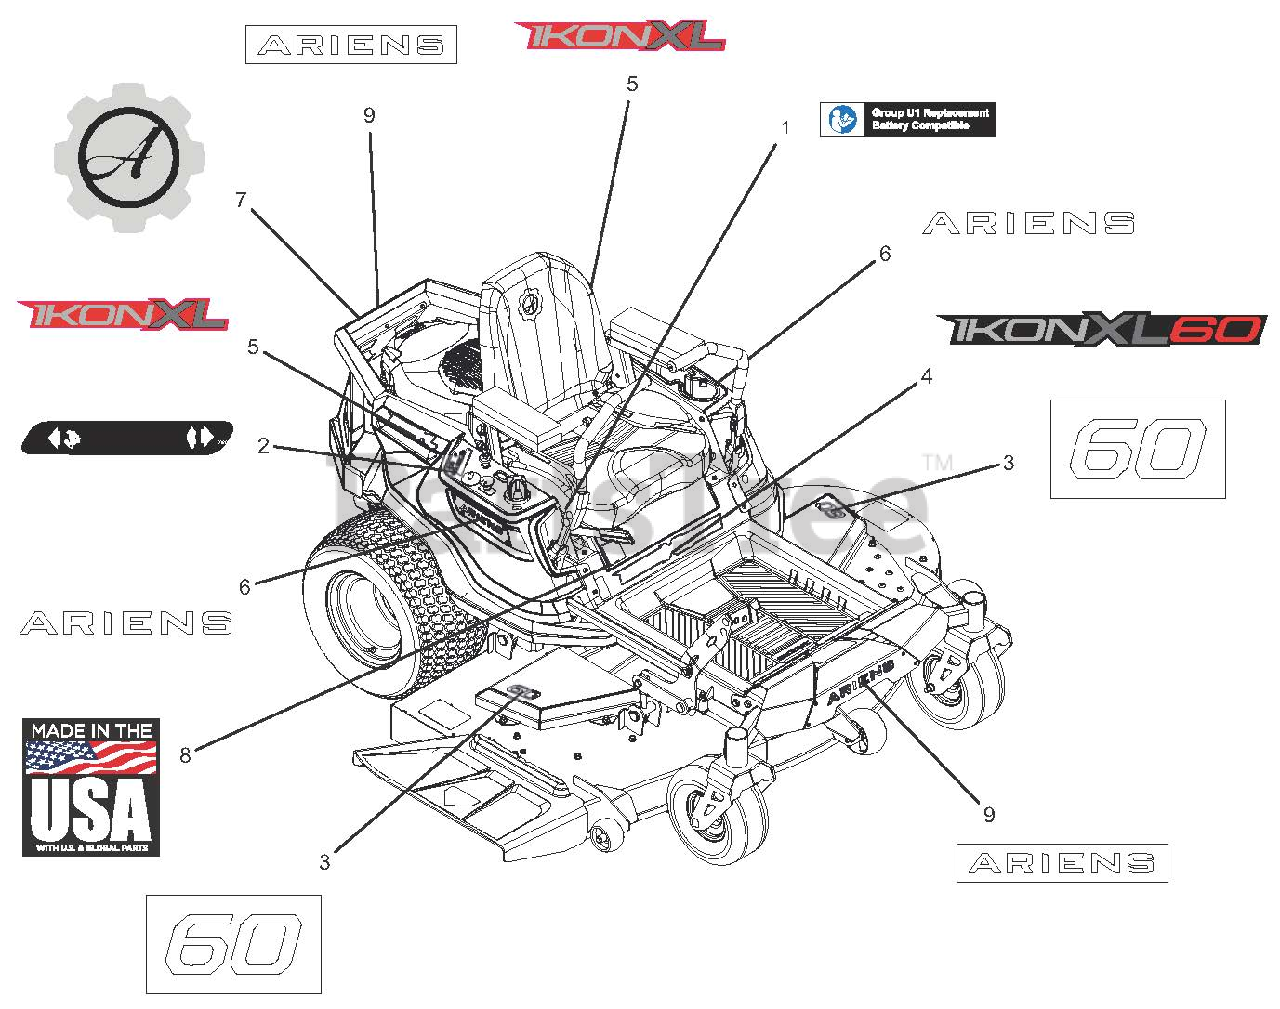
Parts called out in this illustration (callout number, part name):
1	DECAL, U1 BATTERY REPLACEMENT
2	DECAL, DASH DECAL
3	DECAL, 60"
4	DECAL, IKON-XL 60"
5	DECAL, IKON-XL
6	DECAL, ARIENS (6.50")
7	DECAL, ARIENS-GEAR BADGE
8	DECAL, MADE IN USA
9	DECAL - ARIENS 9.625"
